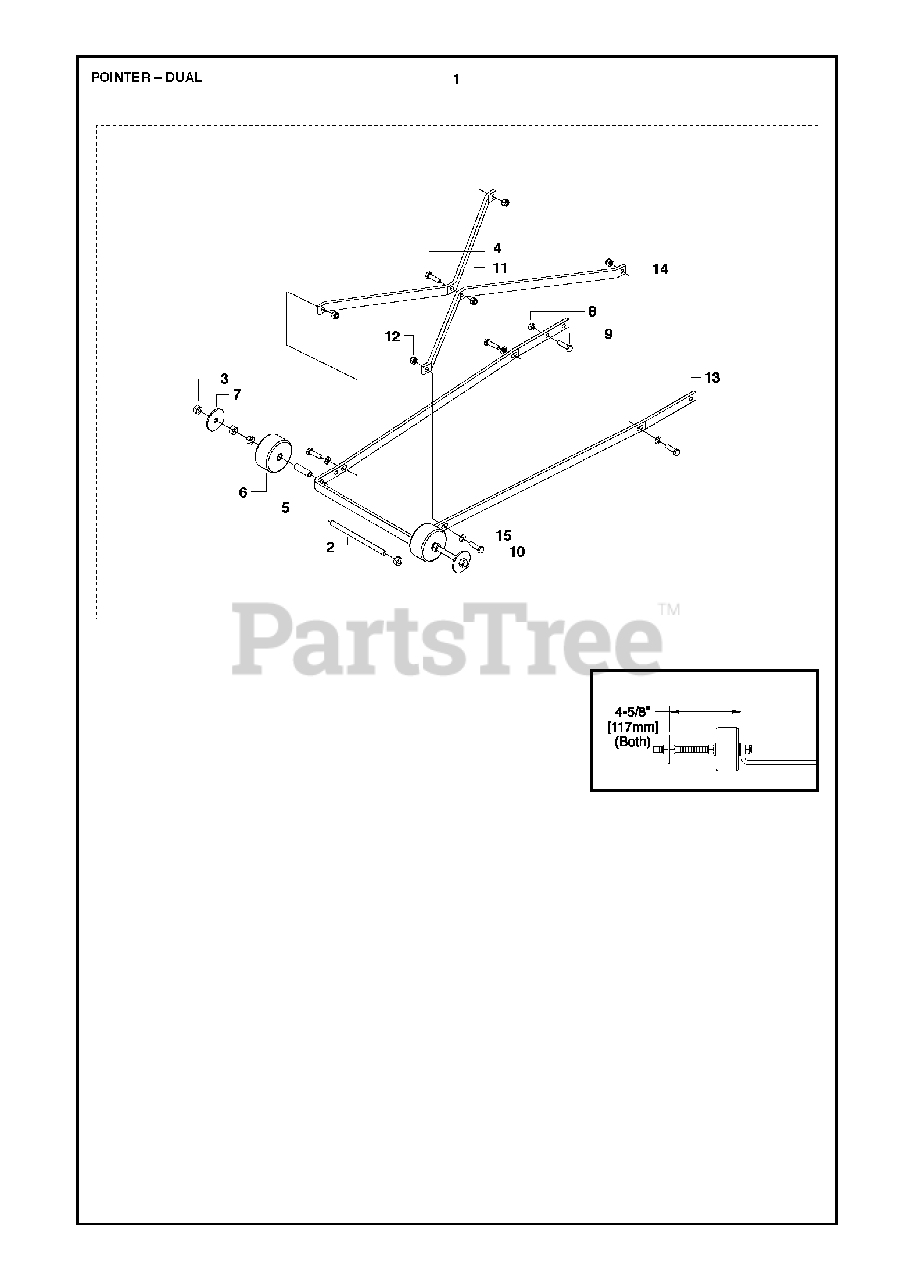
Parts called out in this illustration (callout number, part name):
8	HEXAGON NUT
11	HEXAGON LOCKING NUT
12	HEXAGON LOCKING NUT
13	BAR. OUTSIDE. FINISHED
15	WASHER
